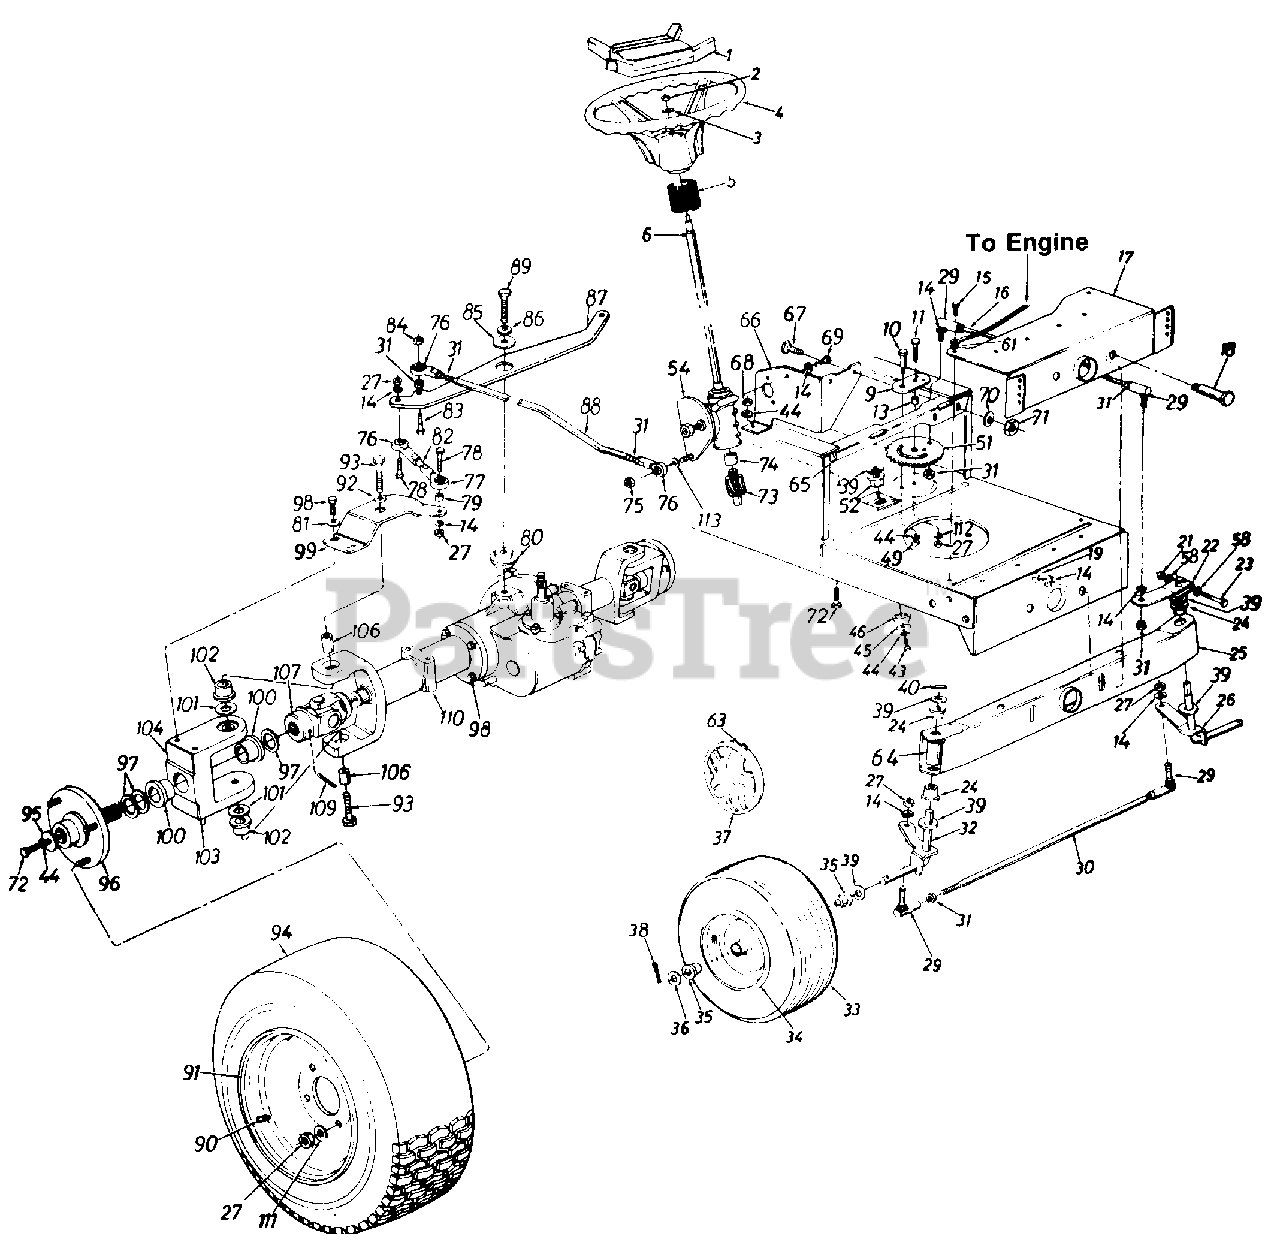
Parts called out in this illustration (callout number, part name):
1	Steering Wheel Insert
2	Hex L-Nut 5/16-24 Thd.
3	Belleville Wash. .345" I.D.
4	Steering Wheel
5	Steering Bellow
6	Steering Shaft Ass'y.
9	Retainer Plate
10	Shoulder Bolt .437" Dia. x .35" Lg. 5/16-18 Thd.
11	Hex Bolt 3/8-24 x 1.0" Lg. (Grade 5)
13	Spacer .380" I.D. x .625" O.D. x .227"
14	L-Wash. 3/8" I.D.
15	Hex Wash. Hd. Self-Tap Scr.
16	Steering Drag Link
17	Front Pivot Brkt.
18	Shoulder Bolt .498" Dia. x 2.04" Lg. 3/8-16 Thd.
19	Hex Nut 3/8-16 Thd.
21	Hex Cent. L-Nut 5/16-24 Thd.
22	Steering Arm Front Axle
23	Hex Bolt 5/16-24 x 2.00" Lg. (Grade 5)
24	Hex Flg. Brg. .634" I.D.
26	Front Axle Ass'y. L.H.
27	Hex Nut 3/8-24 Thd.
29	Ball Joint 3/8-24 Thd.
30	Tie Rod
31	Hex Jam Nut 3/8-24 Thd.
32	Front Axle Ass'y. R.H.
33	Wheel Ass'y. Comp.
34	Front Wheel Rim Only
35	Flange Bearing
36	Fl-Wash. .635" I.D. x 1.59" O.D.
37	Front Hub Cap
38	Cotter Pin 118" Dia. x 1.25" Lg.
39	Fl-Wash. .640" I.D. x .24" O.D.
40	Spring Roll Pin
43	Hex L-Bolt 5/16-18 x .62"
44	L-Wash. 5/16" I.D.
45	Fl-Wash. .33" I.D. x 1.25" O.D.
46	Spacer (Plastic)
49	Hex Nut 5/16-18 Thd.
51	Steering Gear Segment
52	Hex Flg. Brg. .634 I.D.
54	Steering Ass'y. Comp.
58	Wave Wash. .32" I.D. x .62"
61	Ext. L-Wash. 5/16" I.D.
63	Spring Clip
64	Plastic Tube
65	Horizontal Cross Bracket
66	Vertical Mounting Bracket
67	Hex Bolt 1/4-28 x .75" Lg.
68	Hex Nut 5/16-24 Thd.
69	Hex Bolt 3/8-16 x 1.0" Lg.
70	Bell-Wash. .265" I.D. x .75"
71	Hex Nut 1/4-28 Thd.
72	Hex Bolt 5/16-24 x .75" Lg.
73	Pinion Shaft
74	Steering Shaft Splined Coupler
75	Hex L-Nut 3/8-24 Thd.
76	Rod End 3/8-24 Thd. R.H.
77	Rod End 3/8-24 Thd. L.H.
78	Hex Bolt 3/8-24 x 1.5" Lg. (Grade 5)
79	Spacer .38" I.D. x .625"
80	Shld. Spacer .51" I.D.
81	Bell-Wash. .38" I.D. x .88"
82	Tie Rod
83	Hex Bolt 3/8-24 x 1.25" Lg.
84	Hex Patch L-Nut 3/8-24 Thd.
85	Fl-Wash. .531" I.D. x 1.75"
86	Bell-Wash. .505" I.D. x 1.0"
89	Hex Bolt /2-13 x 1.5" Lg. (Grade 5)
90	Air Valve
93	Hex Bolt 1/2-20 x 1.75" Lg. (Grade 5)
95	Fl-Wash. .33" I.D. x 1.25
96	Wheel Flange Ass'y.
97	Fl-Wash. 1.0" x 1.56"
98	Hex Bolt 3/8-24 x 1.25" Lg.
101	Fl-Wash. .76" I.D. x 1.5"
102	Flange Brg. 3/4" I.D.
103	Grease Fitting
104	Wheel Brg. Housing
106	Pivot Sleeve
107	U-Joint
109	Grooved Roll Pin 1.0" Lg.
110	Axle Horn Ass'y.
111	Bell-Wash. .38" I.D. x .88"
112	Bell-Wash. .39" I.D. x 1.38"
113	Fl-Wash. .385" I.D. x .62"
